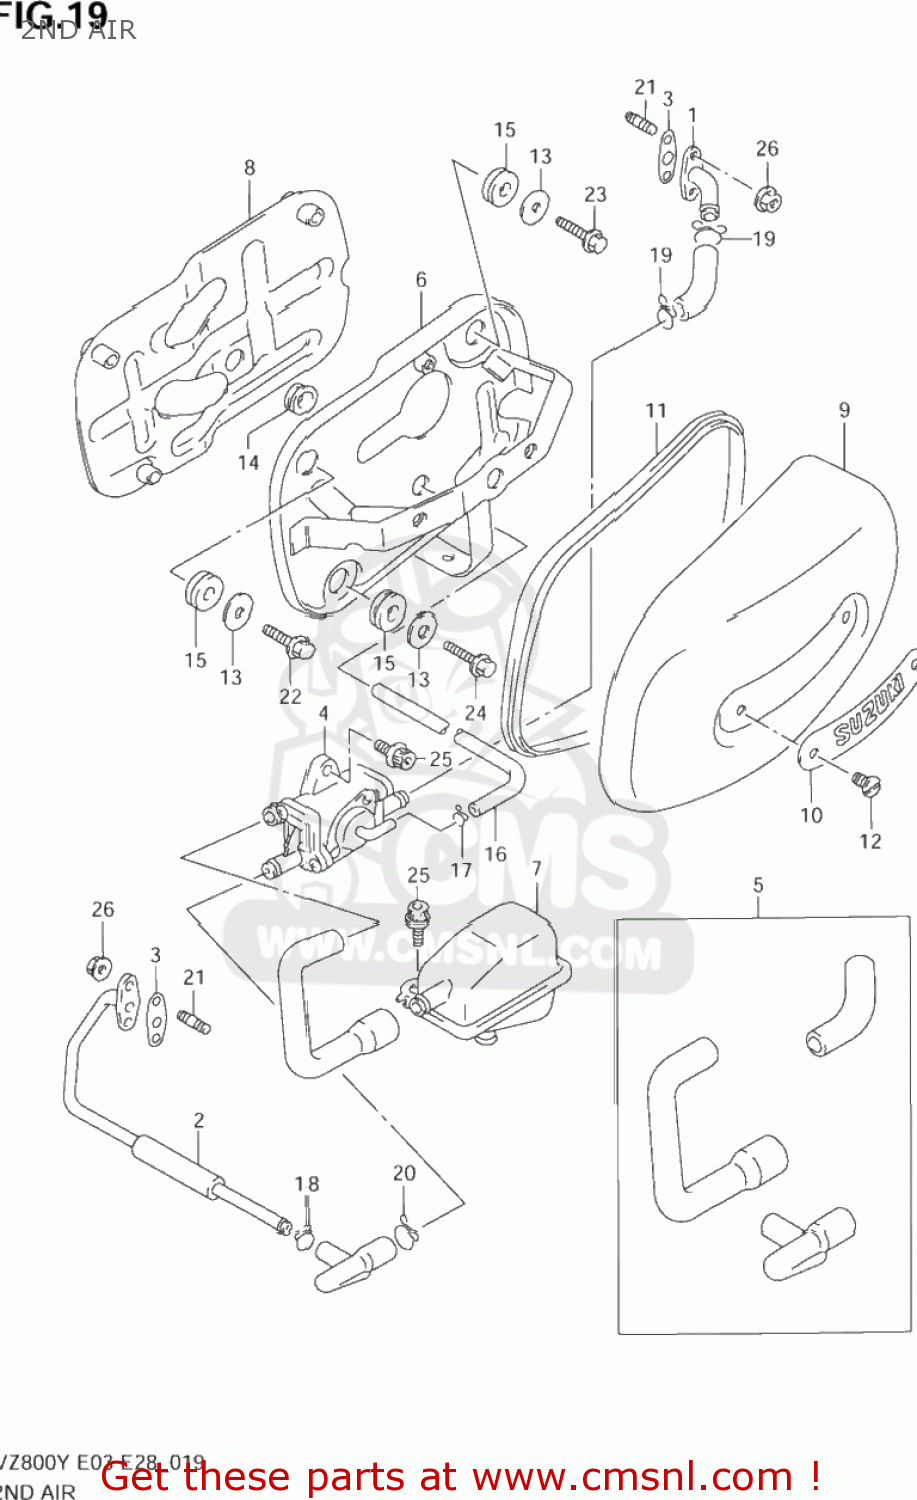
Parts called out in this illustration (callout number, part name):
1	PIPE,2ND AIR FR
2	PIPE,2ND AIR RR
3	GASKET,2ND AIR PIPE (NAS)
4	VALVE ASSY,2ND AIR
5	HOSE SET,2ND AIR
6	BRACKET,2ND AIR SPRT
7	CLEANER,2ND AIR
8	PLATE,2ND AIR HEAT GUARD
9	COVER ASSY,2ND AIR
10	WASHER,2ND AIR COV
11	CUSHION
12	SCREW(6X12)
13	WASHER
14	CUSHION
15	CUSHION
16	HOSE(4X7X600)
17	CLIP
18	CLIP
19	CLIP
20	CLIP
21	STUD BOLT
22	BOLT
23	BOLT
24	BOLT
25	BOLT MAGNETO S
26	NUT
